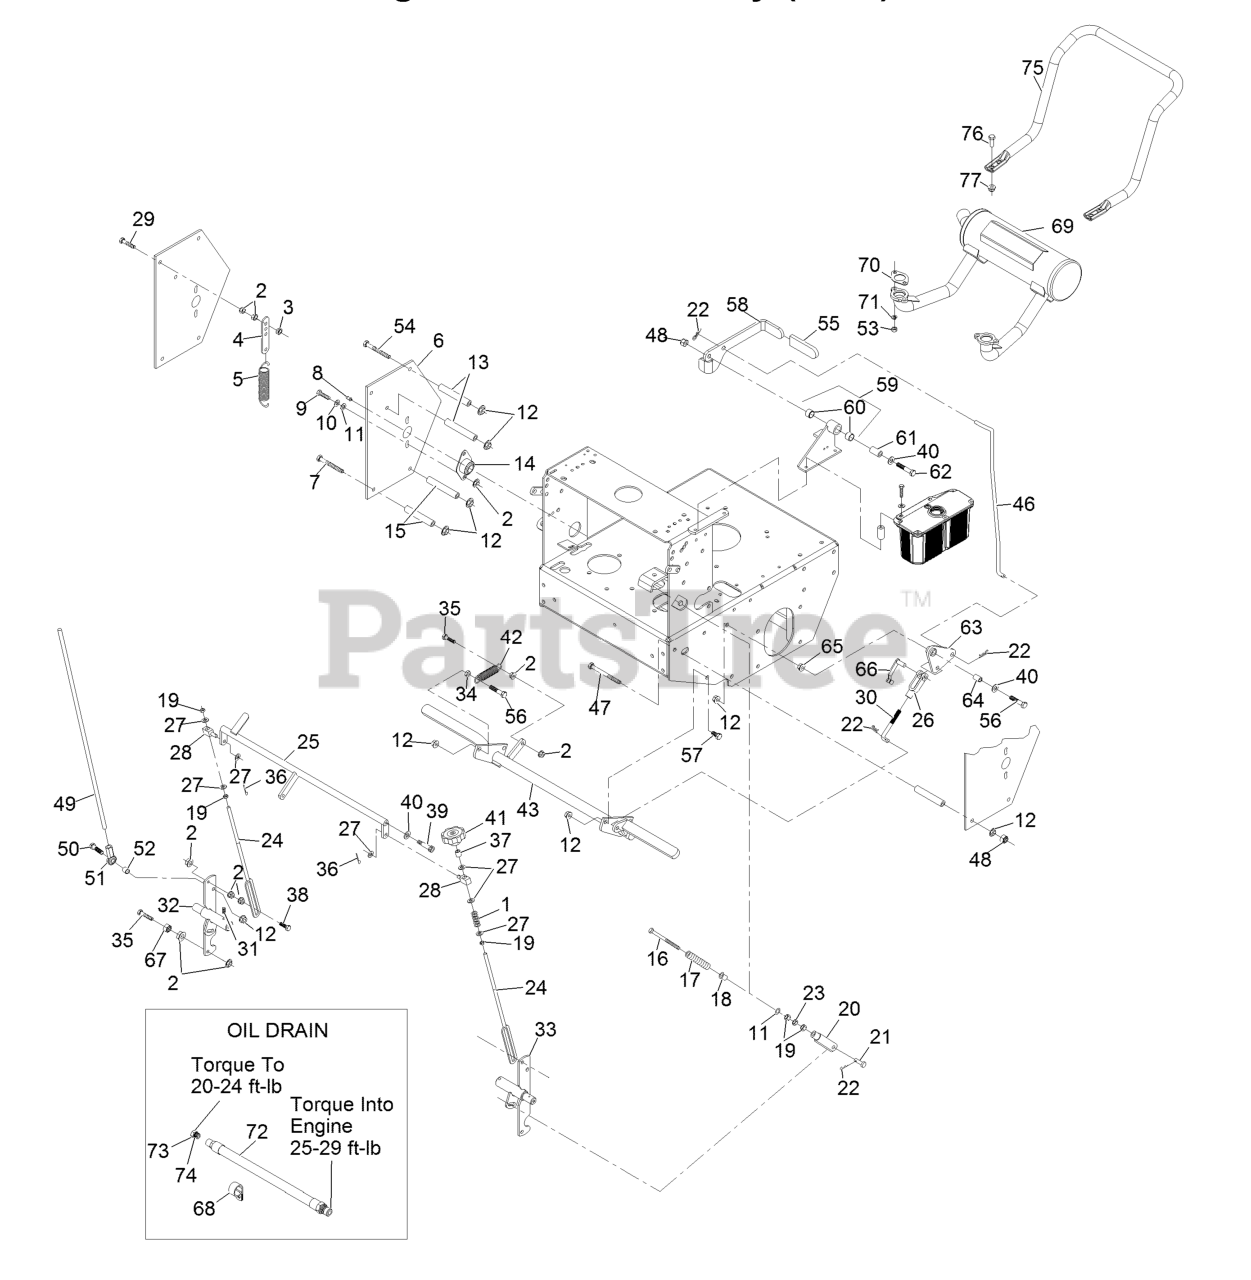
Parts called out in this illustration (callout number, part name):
1	SPRING-COMPRESSION
3	NUT-LOCK, NI
4	TAB-SPRING, EXTENSION
5	SPRING-EXTENSION
6	SHIELD-CONTROL
7	SCREW-HH
8	FITTING-GREASE
9	SCREW-HH
10	WASHER-LOCK
11	WASHER-FLAT
12	NUT-HHF, WHIZ
13	SPACER-SHIELD
14	BEARING-FLANGE, SIDE
15	SPACER-SHIELD
16	BOLT-RETURN, NEUTRAL
17	SPRING,COMPRESSION (NEUT)
18	BUSHING-FLANGED
19	NUT-HEX
20	YOKE-ADJUSTABLE
21	PIN-CLEVIS
22	PIN-COTTER
23	NUT-JAM
24	LINK-CONTROL, SPEED
25	CRANK-CONTROL, SPEED
26	YOKE-LINKAGE, BRAKE
27	WASHER-PLAIN
29	BOLT-TAP, HH
30	LINKAGE-LOWER
31	SCREW-SET
32	SHAFT-CONTROL, LH
33	SHAFT-CONTROL, RH
34	NUT-JAM
35	SCREW-HH, SPECIAL
36	PIN-COTTER
38	SCREW-HH
39	SCREW-HSH
40	WASHER-FLAT
41	KNOB-TRACKING
42	SPRING-IDLER
46	LINKAGE,UPPER- TTHP
47	SCREW-HH
48	NUT-LOCK, NI
49	LINK,DRIVE (PLTD)
50	SCREW-HH
51	JOINT-BALL END, LH
52	SPACER-TUBE, PUMP LINK
54	SCREW-HH
55	GRIP-LEVER
56	SCREW-HH
57	SCREW-HH
58	LEVER,PARK BRK W/DECAL
59	BRACKET ASM
60	SLEEVE-BUSHING
61	BUSHING-PIVOT
62	SCREW-HH
63	BELLCRANK ASM
64	BUSHING-PLASTIC
66	PIN-SPRING, CLEVIS
67	NUT-JAM
68	CLIP-LOOM
69	MUFFLER-HORIZONTAL
70	GASKET-EXHAUST
71	WASHER-LOCK
72	ASM, ENGINE OIL DRAIN HOS
73	PLUG-HH
74	O-RING
75	GUARD-MUFFLER
76	SCREW-HH
77	NUT-HF, NI
